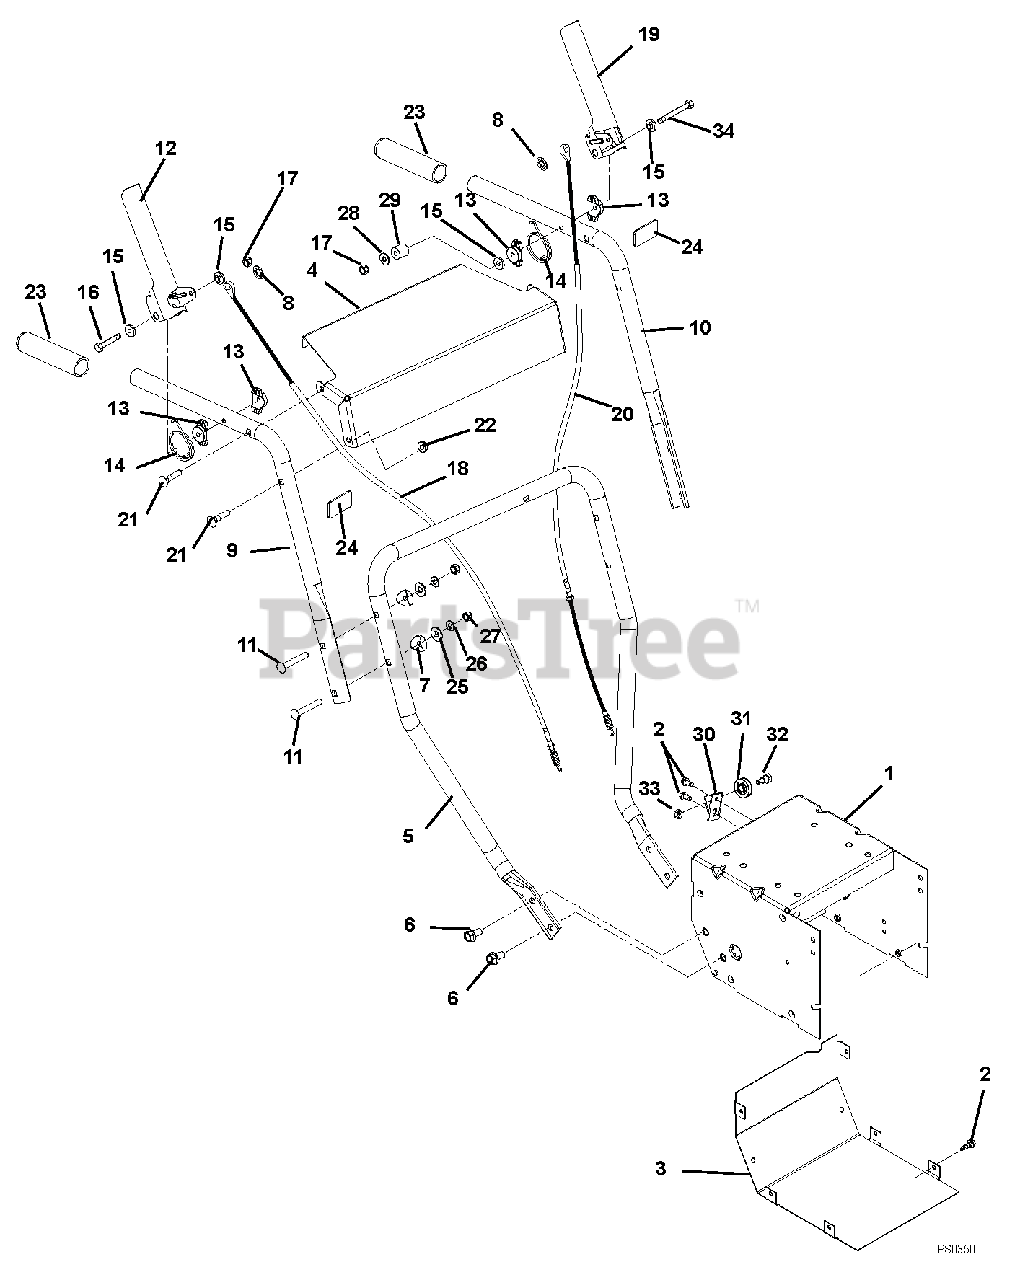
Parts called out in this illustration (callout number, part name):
1	FRAME, WELDMENT
2	@SCR-TAP .25-20X.50 HWH TR YWZ
3	COVER, BOTTOM
4	CONTROL PANEL W/DECAL
5	HANDLEBAR, LOWER
6	BLT-SERHFWH .38-16X.75 YWZC
7	SPACER, HANDLEBAR
8	RG-RTNG-EXT .250X.010
9	HANDLEBAR, UPPER RH
10	HANDLEBAR, UPPER LH
11	@BLT-RDHDSQNK .31-18X2.25 G5YZ
12	PADDLE, CLUTCH - RH COMPACT
13	SPACER, HANDLEBAR
14	SPRING, TORSION
15	BSHG, FLG .266X.42X.150 PM
16	@BLT-HEX .25-20X2.50 GR5 YWZC
17	NUT-JAM-NYL .250-20 W/INSERTYZ
18	AUGER CABLE, ST520 SINGLE SPD
19	PADDLE, CLUTCH - LH COMPACT
20	DRIVE CABLE, ST520 SINGLE SPD
21	BLT-RDHDXLSQNK .31-18X1.5 G5YZ
22	@NUT-LK-TOP-FLG .31-18 YWZC
23	HANDLE GRIP
24	BUMPER PAD
25	@WSHR-FL-STL.38X.875X.083 YWZC
26	@WSHR-LK .31X.078 REG YWZC
27	@NUT-LK-NYL .312-18 YWZC
28	@WSHR-FL-STL.281X.62X.065 YWZC
29	BSHG, SLV .266 X .750 X .750
30	BRACKET, CABLE PULLEY
31	PULLEY, CABLE
32	BOLT, SHLDR-.375X.375X.25-20
33	@NUT-LK-TOP-FLG .25-20 YWZC
34	@BLT-HEX .25-20X3.25 YWZC
